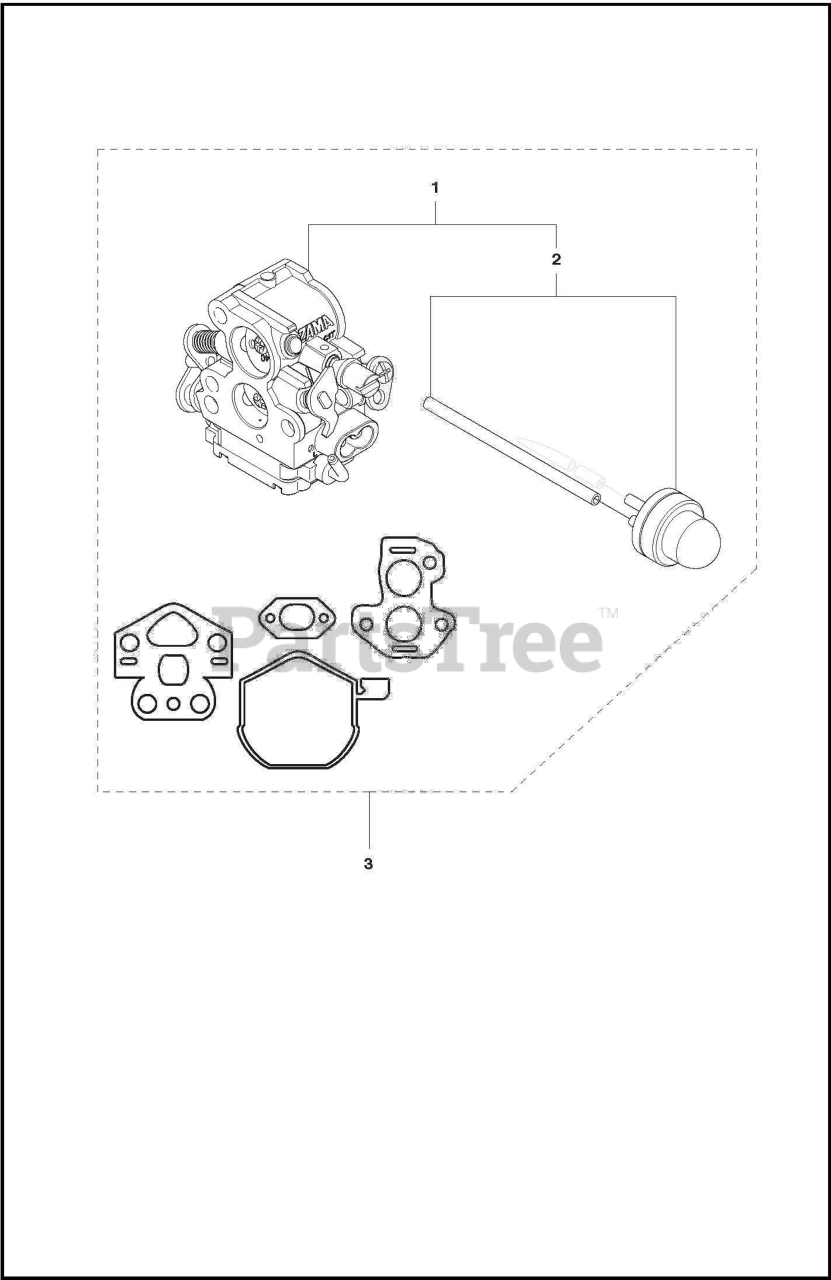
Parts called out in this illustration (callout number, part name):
1	CARBURETTOR 14MM AIR BORE, ANG
2	PURGE & LINE ASSY
3	KIT CARB REPAIR
